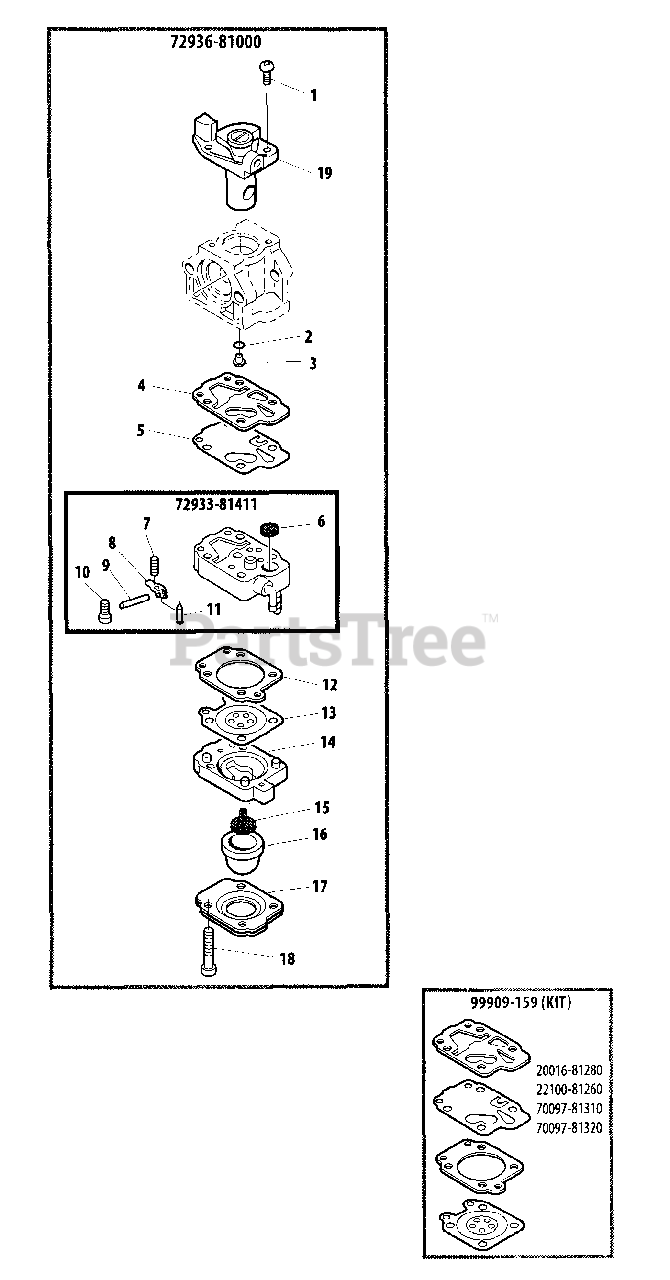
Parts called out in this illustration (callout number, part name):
1	SCREW
2	O-RING
3	JET
4	GASKET, PUMP
5	DIAPHRAGM, PUMP
6	STRAINER
7	SPRING, METERING LEVER
8	LEVER, METERING
9	PIN, METERING LEVER
10	SCREW, METERING LEVER PIN
11	VALVE, INLET NEEDLE
12	GASKET, METERING
13	DIAPHRAGM, METERING
14	BASE, PURGE
15	VALVE, CHECK
16	BULB, PURGE
17	RETAINER, PURGE BULB
18	SCREW, PUMP COVER
19	THROTTLE VALVE ASSY
72933-81411	BASE, PURGE
72936-81000	CARBURETOR
99909-159	DIAPHRAGM/GASKET KIT
